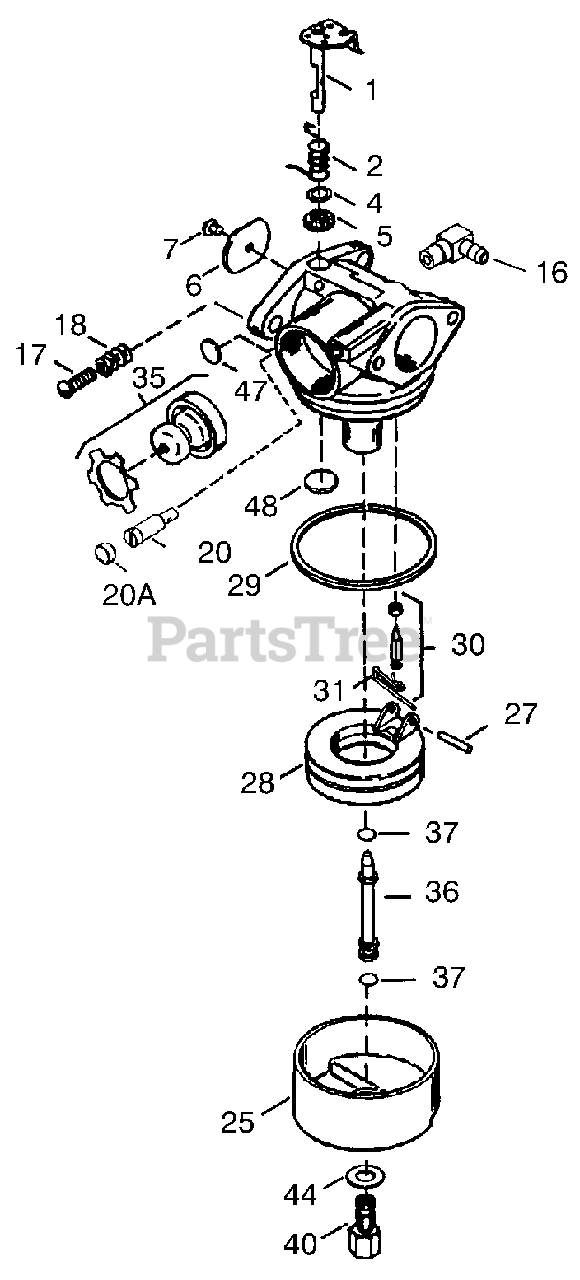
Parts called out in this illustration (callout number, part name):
1	Throttle Shaft & Lever Assembly
2	Throttle Return Spring
4	Dust Seal Washer
5	Dust Seal (Throttle)
6	Throttle Shutter
7	Shutter Screw
16	Fuel Fitting
17	Throttle Crack Screw/ Idle Speed Screw
18	Tension Spring
20	Idle Restrictor Screw
20A	Idle Restrictor Screw Cap
25	Float Bowl
27	Float Shaft
29	Float Bowl "O" Ring
30	Inlet Needle, Seat, & Clip (Incl. 31)
31	Spring Clip
35	Primer Bulb/Retainer Ring
36	Main Nozzle Tube
37	O-Ring, Main Nozzle Tube
40	High Speed Bowl Nut
44	Bowl Nut Washer
47	Welch Plug, Idle Mixture Well
48	Welch Plug, Atmospheric Vent
